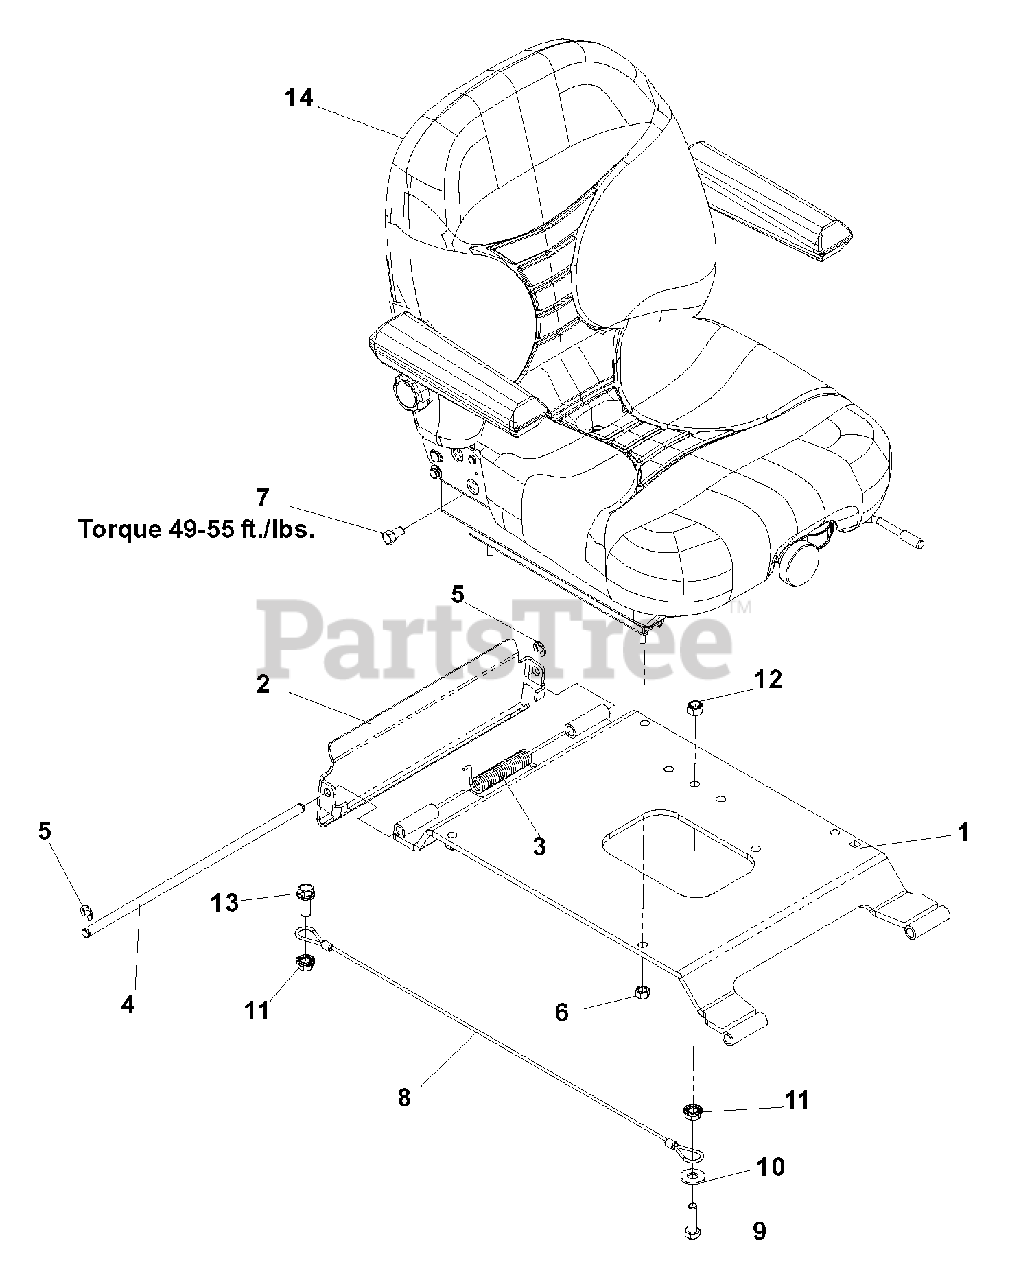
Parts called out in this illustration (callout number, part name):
2	LATCH, SEAT
3	SPRING, TORSION
4	ROD, SEAT LATCH
5	RING, RETAINING
6	NUT, 5/16 -18, NYLOC
7	HCS, 7/16 -20 x 3/4,
8	LANYARD, SEAT
9	HCS, 3/8 -16 x 1 1/4,
10	WASHER, 3/8
11	NUT, 3/8 -16, WHIZLK
12	NUT, 3/8 -16, NYLOC
13	HCS, 3/8 -16 x 1, WHIZLK,
14	SEAT, SUSPENSION
